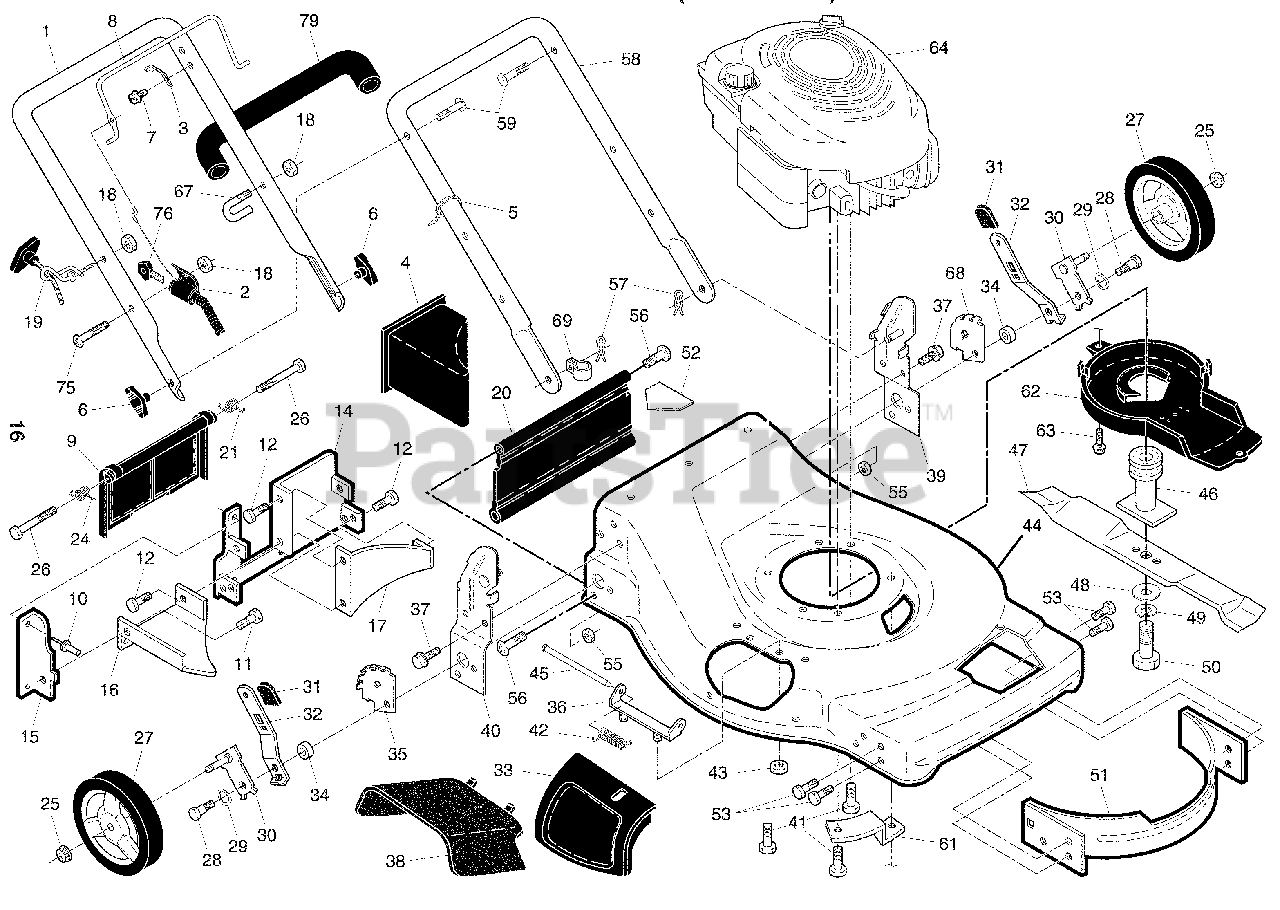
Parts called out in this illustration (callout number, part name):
1	Upper Handle
2	Key Start Switch
3	Bracket, Upstop
4	Mulcher Plug
5	Wire Tie
6	Handle Knob
8	Control Bar
9	Rear Door Assembly
11	Screw, Self-Tapping #10-24 x 5/8
12	Screw, Hex Hex Head, Sems 1/4-20 x 1/2
14	Back Plate
15	Side Baffle
16	Discharge Baffle
17	Rear Baffle
18	Keps Locknut 1/4-20
19	Rope Guide
20	Rear Skirt
21	Spring, Rear Door, LH
24	Spring, Rear Door, RH
25	Nut, Hex, Flanged
26	Bolt, Rear Door
27	Wheel & Tire Assembly, Rear
28	Bolt, Shoulder 3/8-16 x 1
29	Washer, Belleville
30	Axle Arm Assembly
31	Selector Knob
32	Selector Spring
33	Mulcher Door
35	Wheel Adjusting Bracket, RH
36	Hinge Bracket Assembly
37	Screw, Sems, Thread Cutting 5/16-18 x 3/4
38	Discharge Deflector
39	Handle Bracket Assembly, LH
40	Handle Bracket Assembly, RH
41	Screw, Hex Head, Threaded, Rolled 3/8-16 x 1-1/8
42	Spring, Torsion
43	Nut, Hex, Nylock
44	Kit, Lawn Mower Housing
45	Rod, Hinge
46	Blade Adapter / Pulley
47	Blade, 22"
48	Washer, Hardened
49	Washer, Helical
50	Screw, Machine, Hex Head 3/8-24 x 1-3/8 Grade
51	Front Baffle
52	Danger Decal
55	Nut, Hex
56	Screw, Hinge 1/4-20 x 1-1/4
57	Hairpin Cotter
58	Lower Handle
59	Handle Bolt
61	Bracket Debris Shield
62	Debris Shield
63	Screw, Debris Shield
67	Clip, Packaging
68	Wheel Adjusting Bracket, LH
69	Clip, Cable
